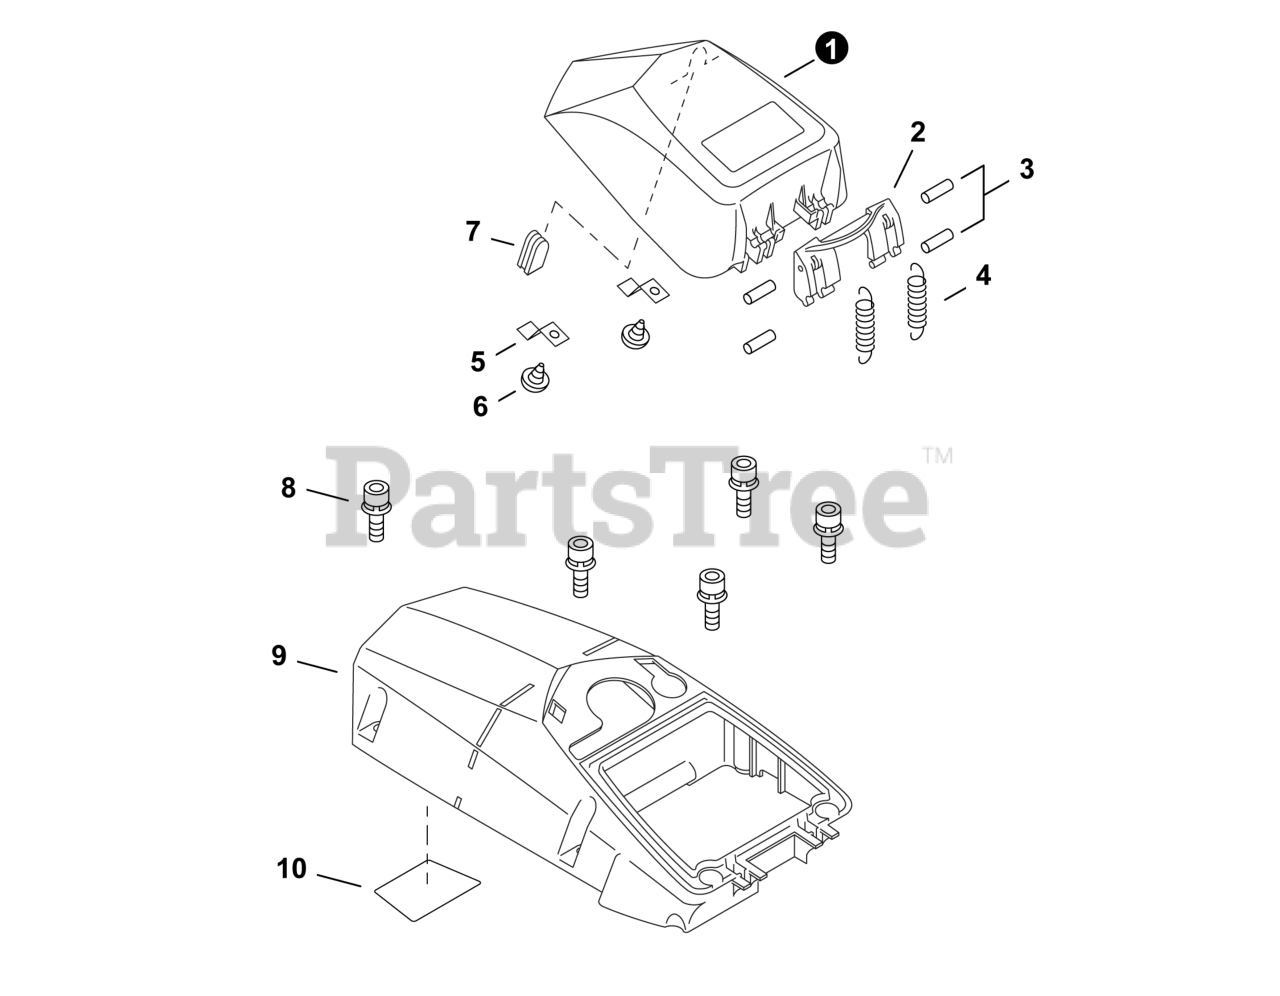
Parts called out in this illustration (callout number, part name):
1	COVER, AIR FILTER
2	LATCH, FILTER COVER
3	PIN 3×12
4	SPRING, TENSION
5	SPRING, FLAT
6	SCREW 4×10
8	BOLT 5×20
9	COVER, ENGINE
10	SHIELD, HEAT
